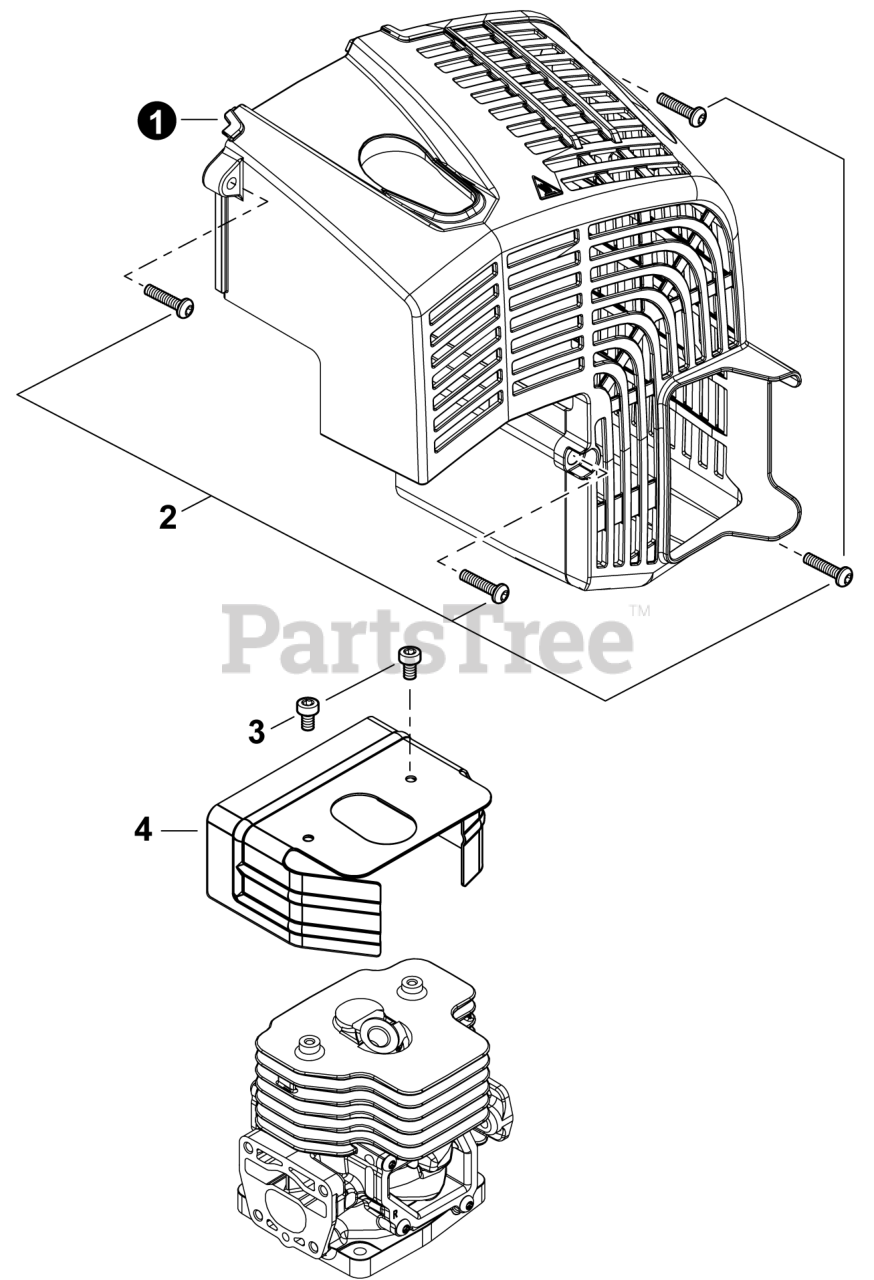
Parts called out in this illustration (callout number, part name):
1	COVER, ENGINE
2	BOLT, TORX 5×20
3	BOLT, TORX 4×8
4	COVER, CYLINDER
